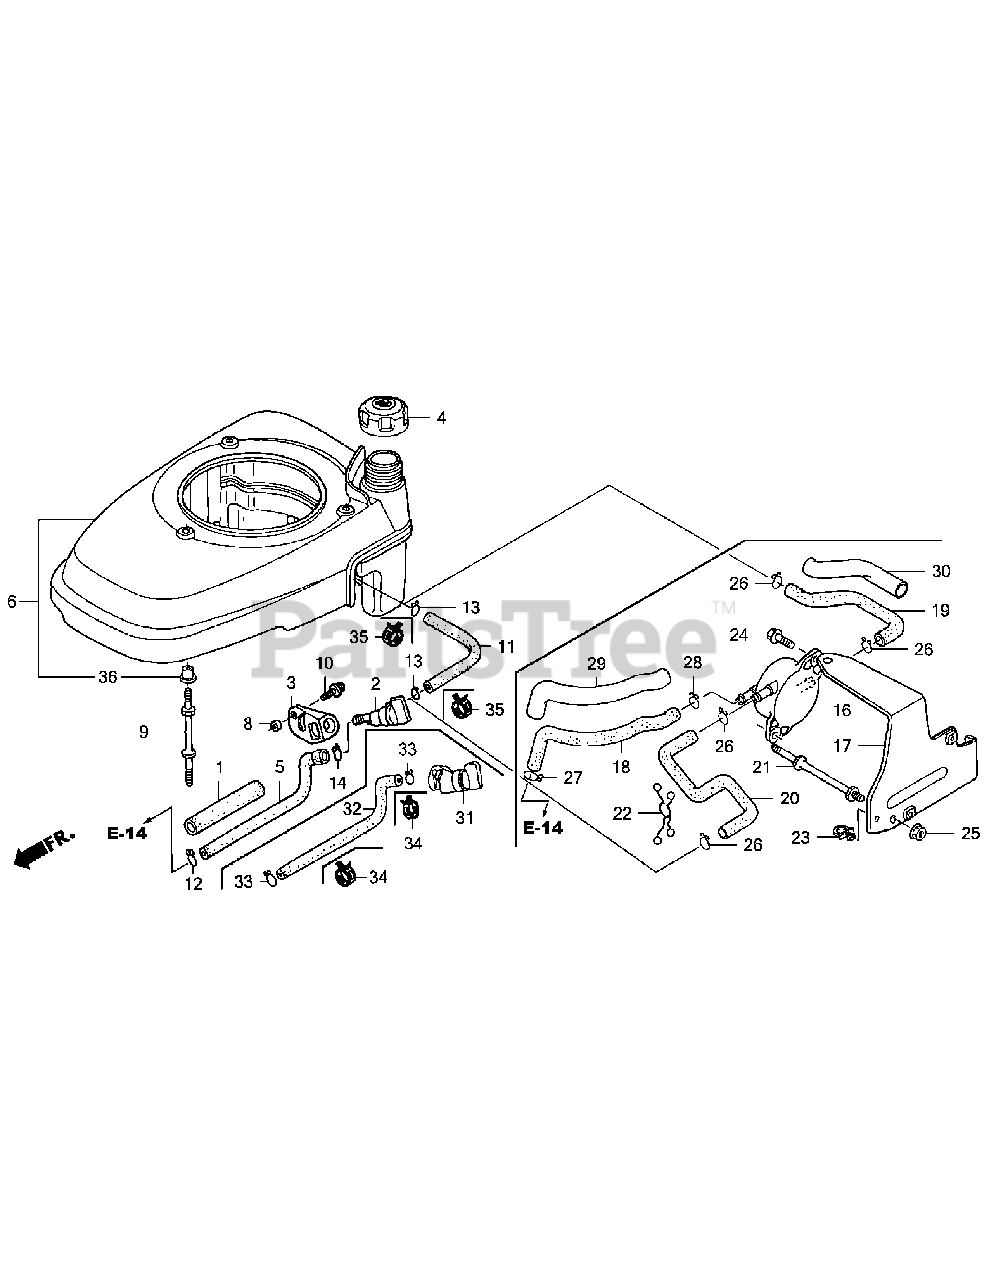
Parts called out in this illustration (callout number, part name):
1	RUBBER, SUPPORTER (107MM)
4	CAP ASSY., FUEL TANK
6	COVER, FAN *NH1* (BLACK)
8	COLLAR, FUEL PETCOCK
9	BOLT, STUD
10	SCREW-WASHER (5X10)
11	TUBE, FUEL (5.3X150) (FKM)
31	PETCOCK ASSY
32	TUBE, FUEL (FKM)
34	CLIP, TUBE (D8)
35	CLIP, TUBE (D10)
36	COLLAR, FAN COVER (N/A: SEE ASSEMBLY)
